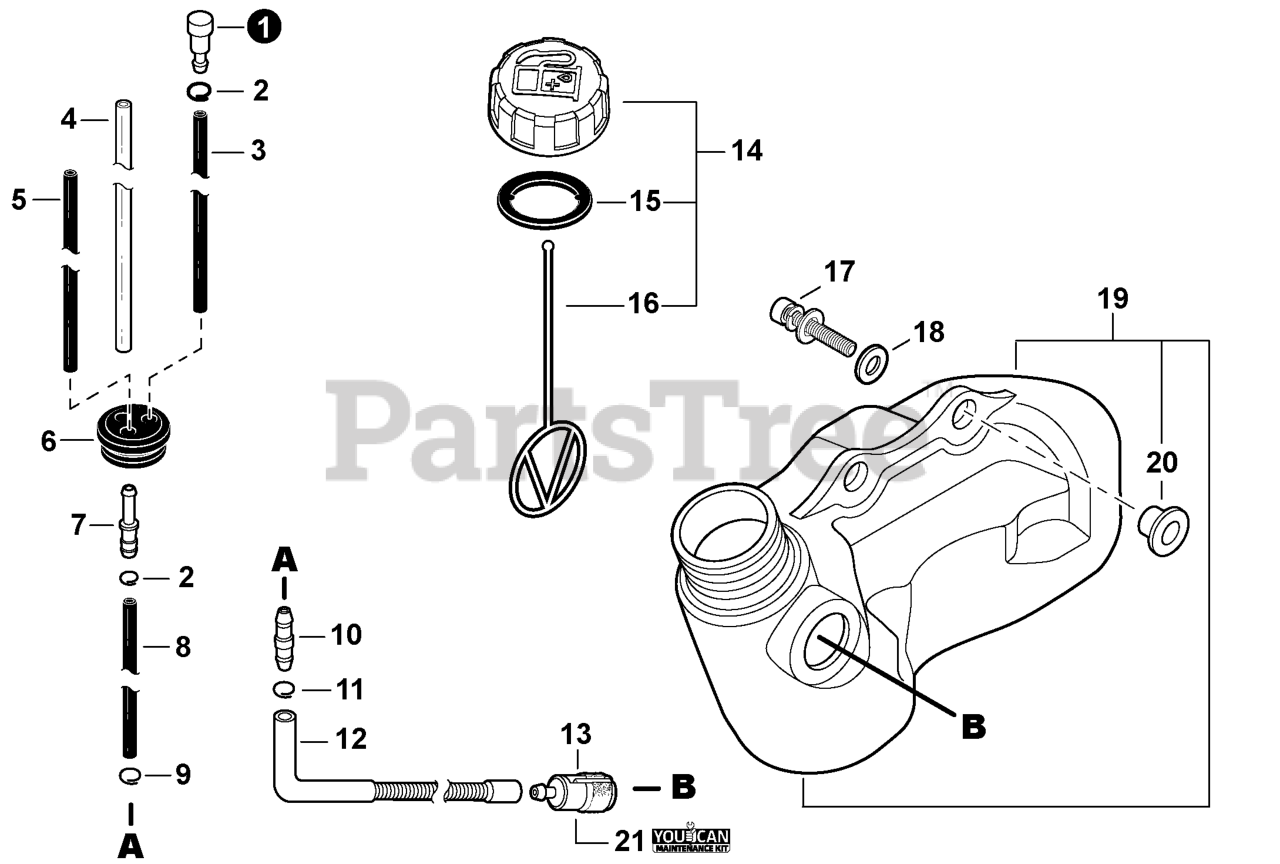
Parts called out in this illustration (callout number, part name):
1	VENT ASSY
2	CLIP 6.5 MM
3	PIPE, FUEL 3x6x50 BLACK
4	PIPE, FUEL 3x6x75 CLEAR
5	PIPE, FUEL 3x5.5x61 BLACK
6	GROMMET, FUEL
7	CONNECTOR, PIPE 5x3.5
8	PIPE, FUEL 3x6x35 BLACK
10	CONNECTOR, PIPE
11	CLIP 6.6 MM
12	PIPE, FUEL 3x7x100 FLEXIBLE
13	FILTER, FUEL
14	CAP ASSY, FUEL
15	GASKET, FUEL CAP
16	CONNECTOR, CAP L= 123
17	BOLT 5x20
18	WASHER 5.5x12x0.8
19	TANK, FUEL
20	COLLAR 5
21	TUNE-UP KIT - YOUCANT
